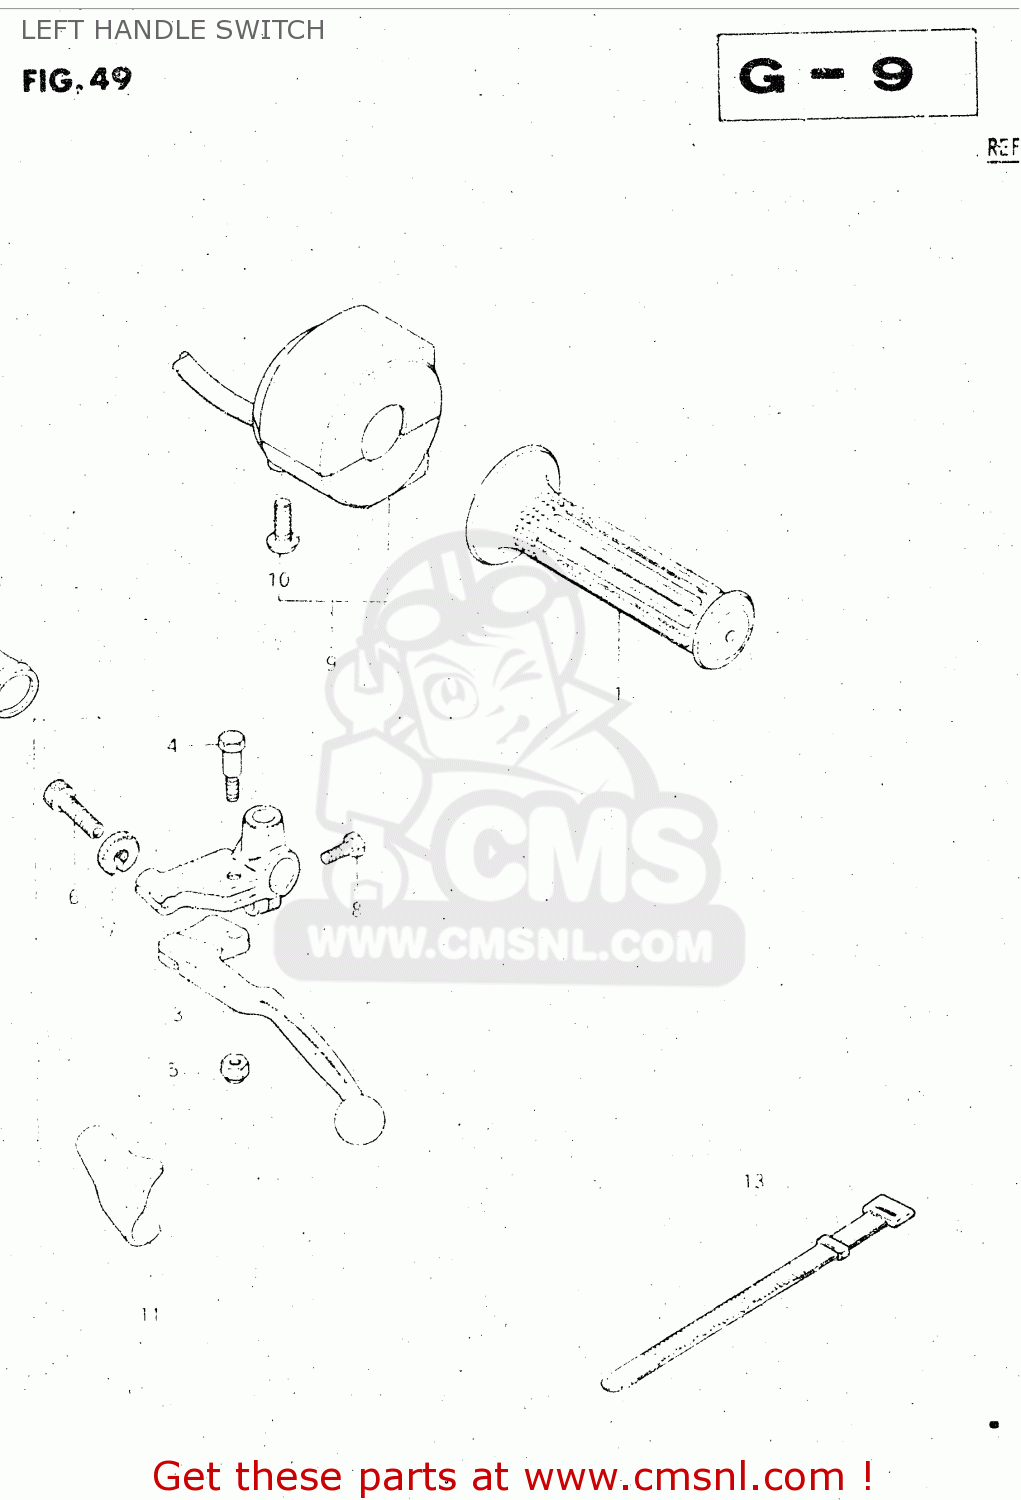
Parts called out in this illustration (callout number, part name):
1	GRIP,LEFT
2	LEVER ASSEMBLY
3	LEVER,CLUTCH
4	BOLT,LEVER
5	NUT 6MM
6	ADJUSTER,CABLE
7	NUT,CABLE ADJUSTER
8	BOLT
9	SWITCH ASSY, HANDLE LH
10	SCREW
11	COVER,CLUTCH LEVER
12	BOOT,CLUTCH CABLE
13	CLAMP(L:120)
